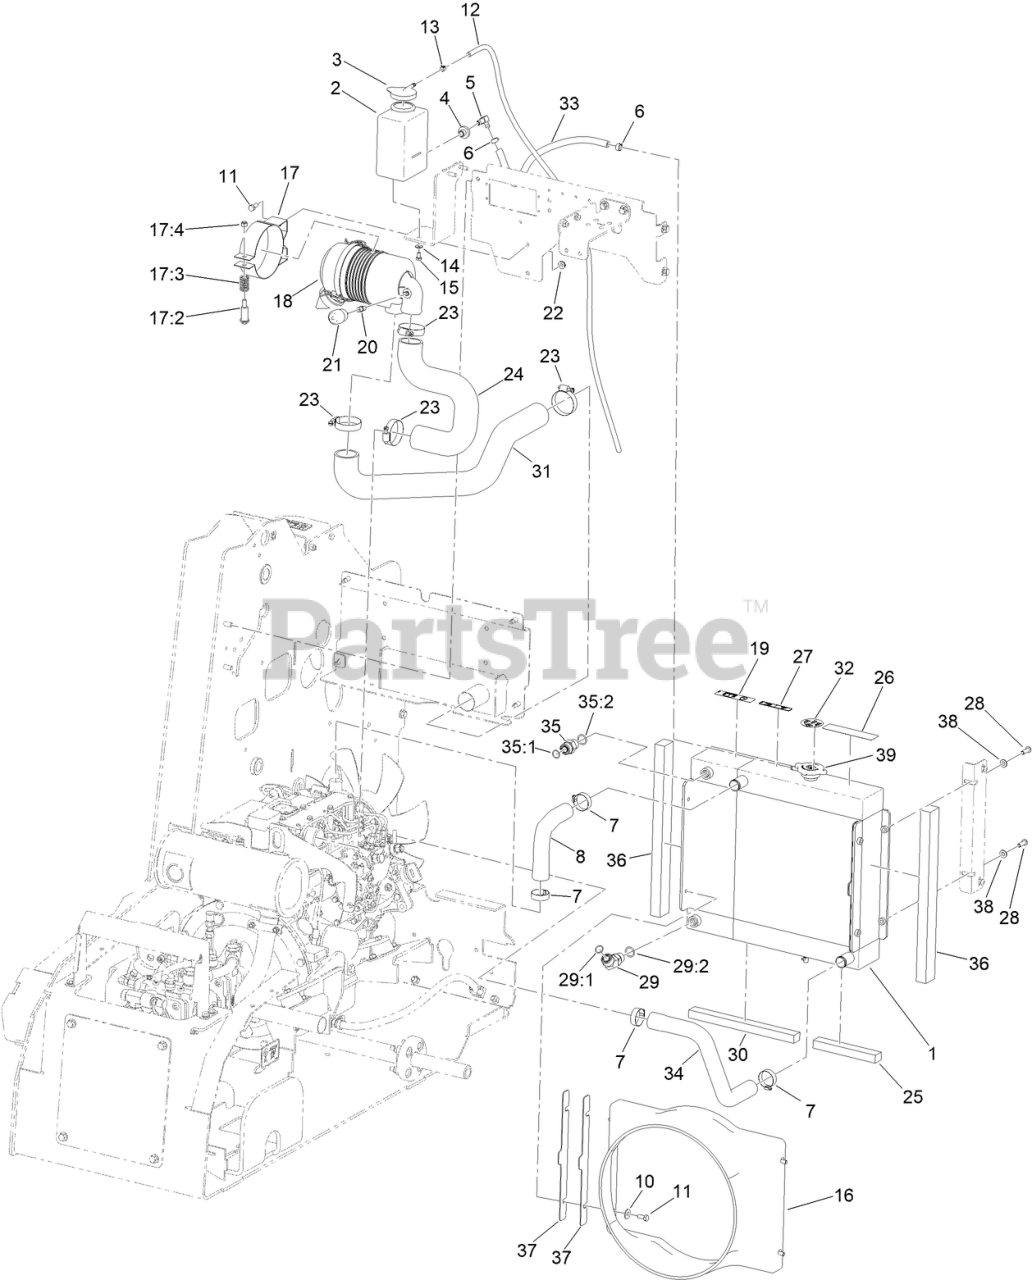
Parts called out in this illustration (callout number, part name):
1	RAD/OIL COOLER
2	TANK-OVERFLOW
3	CAP-TANK, OVERFLOW
4	BUSHING
5	FITTING-ELBOW, 90 DEG
6	CLAMP-HOSE
7	CLAMP-HOSE
8	HOSE-RADIATOR, UPPER
10	WASHER-FLAT
11	SCREW-HH
12	HOSE-FUEL
13	CLAMP-HOSE
14	WASHER-FLAT
15	SCREW-HH
16	SHROUD-FAN
17	AIR CLEANER MOUNTING BAND ASM
17:3	SPRING
17:4	NUT-LOCK, NI
18	AIR CLEANER ASM
19	DECAL-RADIATOR FILL
20	NIPPLE-PIPE
21	INDICATOR
22	NUT-HF
23	CLAMP-HOSE
24	HOSE-AIR, INLET
25	FOAM-RADIATOR BOTTOM LH
26	DECAL-DANGER
27	DECAL-WARNING, FAN
28	SCREW-HSBH
29	FITTING-HYD, 45 DEG
29:1	O-RING
29:2	O-RING
30	FOAM-RADIATOR BOTTOM RH
31	HOSE-AIR, INLET
32	DECAL-DANGER
33	HOSE-FUEL
34	HOSE-RADIATOR, LOWER
35	FITTING-STRAIGHT
35:1	O-RING
35:2	O-RING
36	FOAM-RADIATOR SIDE
37	SPACER-RADIATOR
38	WASHER-PLAIN
39	CAP-RADIATOR
